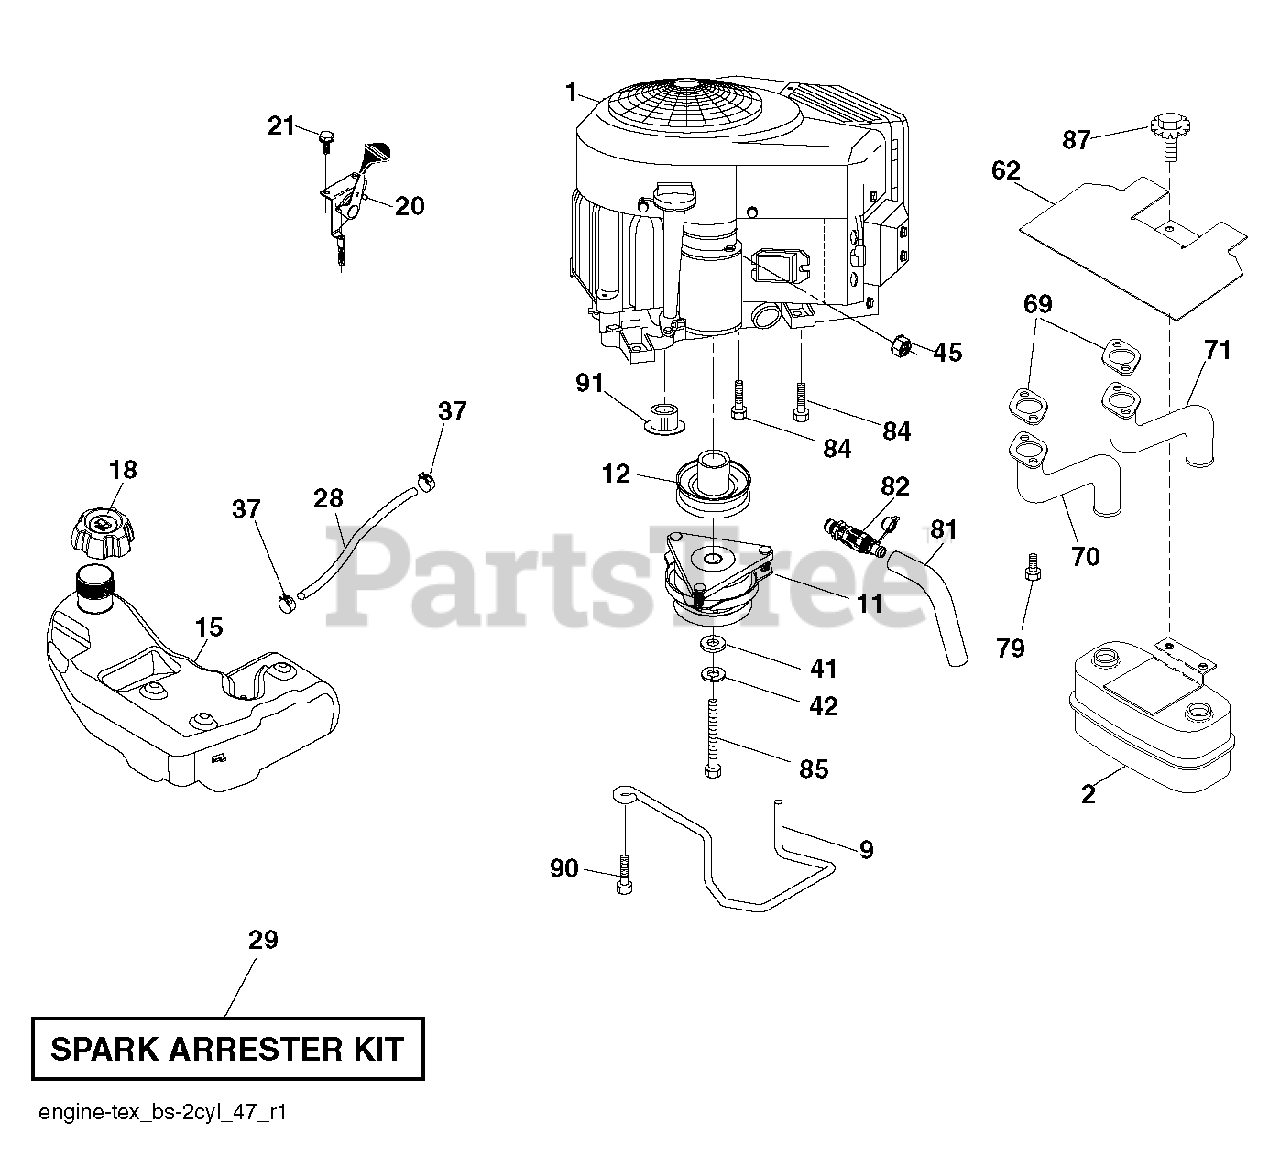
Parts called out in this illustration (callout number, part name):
2	MUFFLER.ASM.TWN.EXTNDED.DFLCTR
9	KEEPER.BELT.ENGINE.4.2
11	CLUTCH.ELECTRIC.LT.48"*
12	PULLEY.ENGINE.TUFFTORQ
15	TANK.ASSY.3.GAL.EPA
18	CAP.ASM.FL.RITCH.3"E10.SYM.498
20	CONTROL.TH/CK.COBRA.B&S.TWN.
21	SCREW.#10 X 0.750.BOS
28	LINE.FUEL.64"REAR.EMIS
29	KIT.SPARK ARRESTOR 794945 B&S
37	HOSE CLAMP
42	LOCKWASHER
45	NUT
62	SHIELD.HEAT.MUFFLER
69	GASKET.MUFFLER
70	RP.EXHAUST.TUBE.LH.BS/TWIN
71	EXHAUST.TUBE.RH.BS/TWIN
79	SCREW.SOCKET.HEAD.5/16-18
81	TUBE, DRAIN OIL ASM.
82	VALUE.OIL.DRAIN
84	SCREW.3/8-16
85	BOLT HEX 7/16-20X4-1/4"
87	BOLT, 5/16-18 X 1 3/4
90	SCREW 3/8-16X1
91	BUSHING.1.375OD
